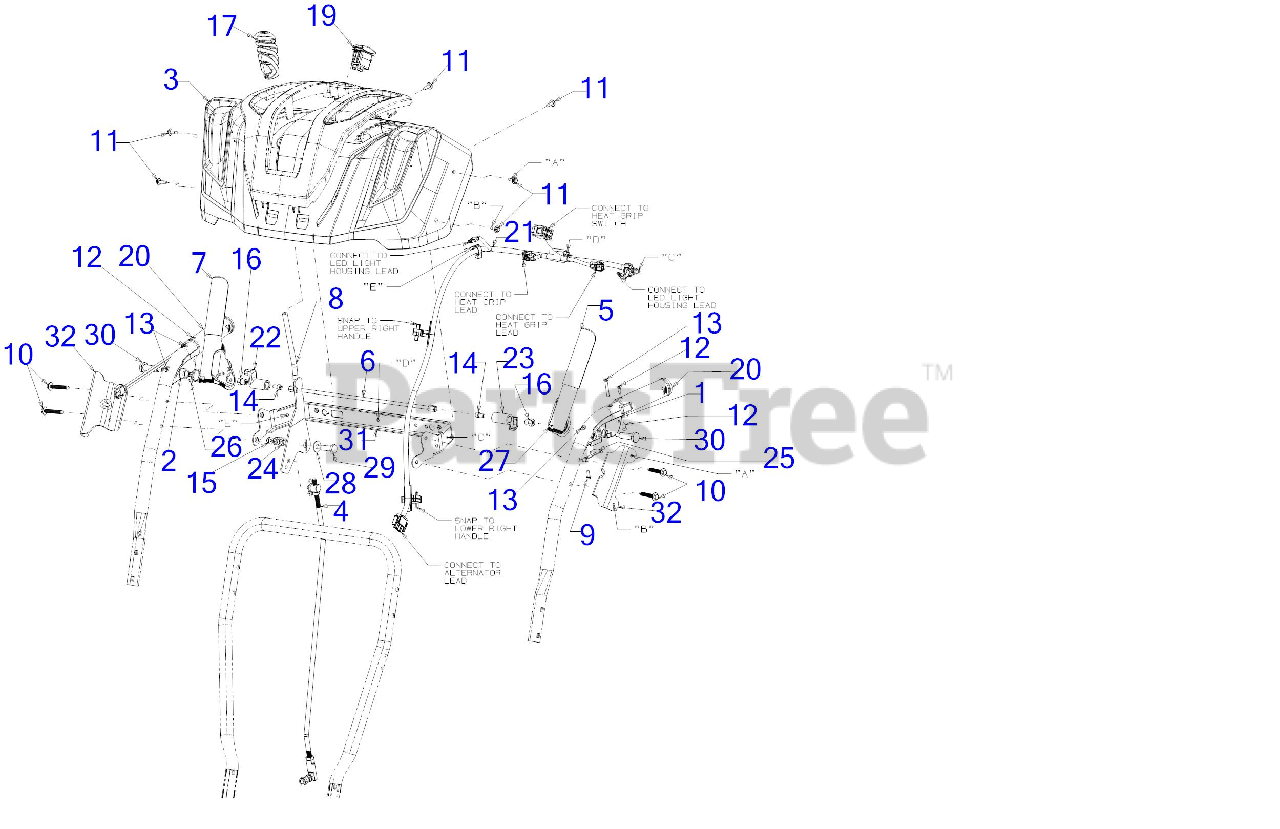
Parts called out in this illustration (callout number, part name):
1	CLUTCH LOCK HANDLE ASSEMBLY (LH)
2	CLUTCH LOCK HANDLE ASSEMBLY (RH)
3	HANDLE PANEL ASSEMBLY
4	SHIFT ROD ASSEMBLY
5	HANDLE ASSEMBLY (LH)
7	HANDLE ASSEMBLY (RH)
9	SCREW #8-16 x .50
10	SCREW 1/4-20 x 1.625
11	SCREW M6-1 x .625
12	SCREW #10-16 x .625
13	SCREW #10-24 x 1.375
14	SCREW 1/4-20 x .50
15	FLANGE LOCK NUT
16	HEX NUT W/PATCH
17	PTO HANDLE GRIP .355 ID
19	HEATED GRIP SWITCH
20	HARNESS-SNOW HEATED GRIP RED
21	HARNESS-TWO HEADLIGHT
23	CLUTCH LOCK CAM
24	COMPRESSION SPRING
25	CLUTCH SPRING
26	TORSION SPRING
27	RUBBER BUMPER
28	FLAT WASHER
29	SHOULDER SCREW
30	SHOULDER SCREW .437 x 1.345 1/4-20
